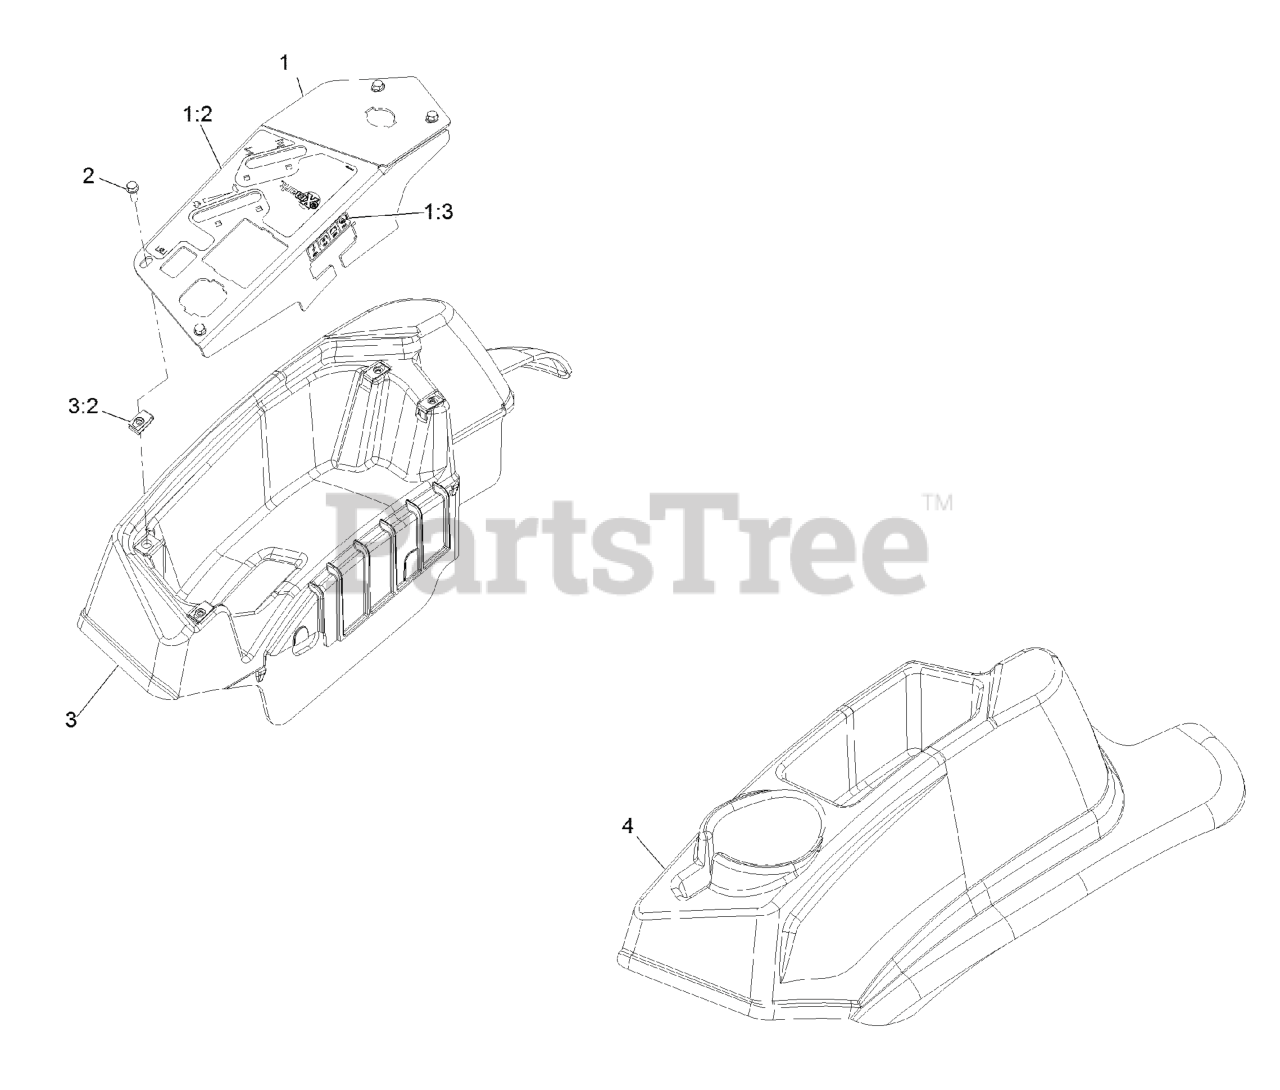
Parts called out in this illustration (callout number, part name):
1	ASM-PANEL, CONTROL W/DECA
1:2	DECAL-CONTROL PANEL NON-E
1:3	DECAL-FUSES
2	SCREW-HWH
3	CONSOLE,RH AS ASM
4	CONSOLE, LH AS
